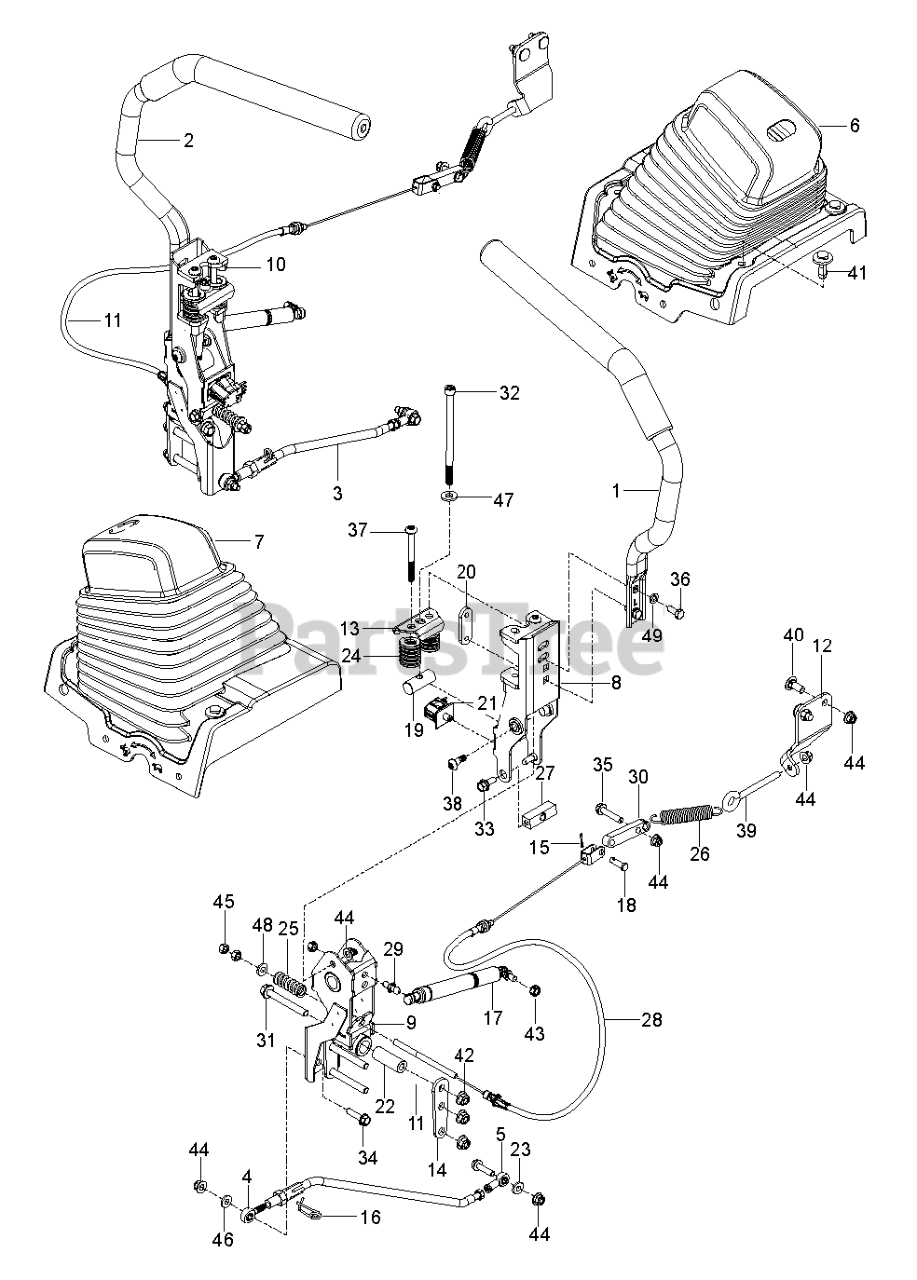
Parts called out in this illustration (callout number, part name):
1	LEVER.ASM.DRIVE.LH
2	LEVER.ASM.DRIVE.RH
3	ROD.ASM.CONTROL.PZ.5400.LH
3	KIT.CONTROL.LINKAGE.LEFT
3	KIT.CONTROL.LINKAGE.RIGHT
4	ROD.END.MALE.LH.THREAD
5	JOINT.HEIM.FEML.5/16.RH.THREAD
6	KIT.SERVICE.LEVER.BELLOW.LH
6	BELLOWS.LH.DRIVE.LEVER
7	BELLOWS.RH.DRIVE.LEVER
7	KIT.SERVICE.LEVER.BELLOW.RH
8	KIT.CARRIER.UPPR.W/BUSHINGS.RT
8	KIT.CARRIER.UPPR.W/BUSHINGS.LT
9	KIT.CARRIER.LWR.W/BUSHINGS
10	KIT.CONTROL.MECHANISM.RIGHT
10	KIT.CONTROL.MECHANISM.LEFT
11	KIT.CABLE.BRAKE.PARKING.LEFT
12	BRACKET.PNT.RETRN.SPRNG.RH.BLK
12	BRACKET.PNT.RETRN.SPRNG.LH.BLK
13	BRACKET.RETAINING.SPRING
14	BRACKET.PNT.CONTROLS.MTG.EDIP
15	PIN COTTER;LOCKING;BOWTIE;1IN
16	CLIP.RETAINER.CONTROLS
18	PIN.CLEVIS.5/16.DIA.3/4.USABLE
21	SWITCH.SNPMNT.DELTA.NCNC.PZREF
22	SPACER.PIVOT
23	SPACER.7_16OD;5_16ID;STEP.UP
24	SPRING 1.25"ODX1.5"L
25	SPRING, BRAKE ROD
26	SPRING.RETURN.BRAKE
27	CABLE.YOKE.PARK.BRAKE
28	CABLE.BRAKE.PARK
29	STUD.BALL.10MM
30	BRACKET.EXTENSION
31	BEARING.FLG.3/8.SHAFT.1/2.HSG
32	BEARING, FLANGE
33	BOLT, SHOULDER
34	HHFS 5/16-18 X 1.25 TPBLT GD 5
35	HHFS 5/16-18 X 1.5 GD 5
36	HCS 5/16C X 3/4
37	SCREW.SHCS.5/16-18 X 3-1/2"
38	SCREW.SHLDR.3/8 X 1/2.5/16-18
39	EYE BOLT 5/16 X 3.50
40	RHSNB 5/16C X 1
41	HHFS 3/8-16 X 3 GRD 5 ZD
42	SCREW.SHCS.3/8-16 X 6L.ZY
43	RIVET.PUSH.PIN.0.25IN.HOLE
44	5/16-18 NYLOC FLANGE NUT
46	NUT 3/8-16 HEX FLG NYLOC ZD
47	NUT 5/16C CENTERLOCK
48	WASHER 5/16 FLAT
49	WASHER.LOCK.HVY.HLCL.SPR.5/16
50	WASHER
51	WASHER, 3/8 THICK
